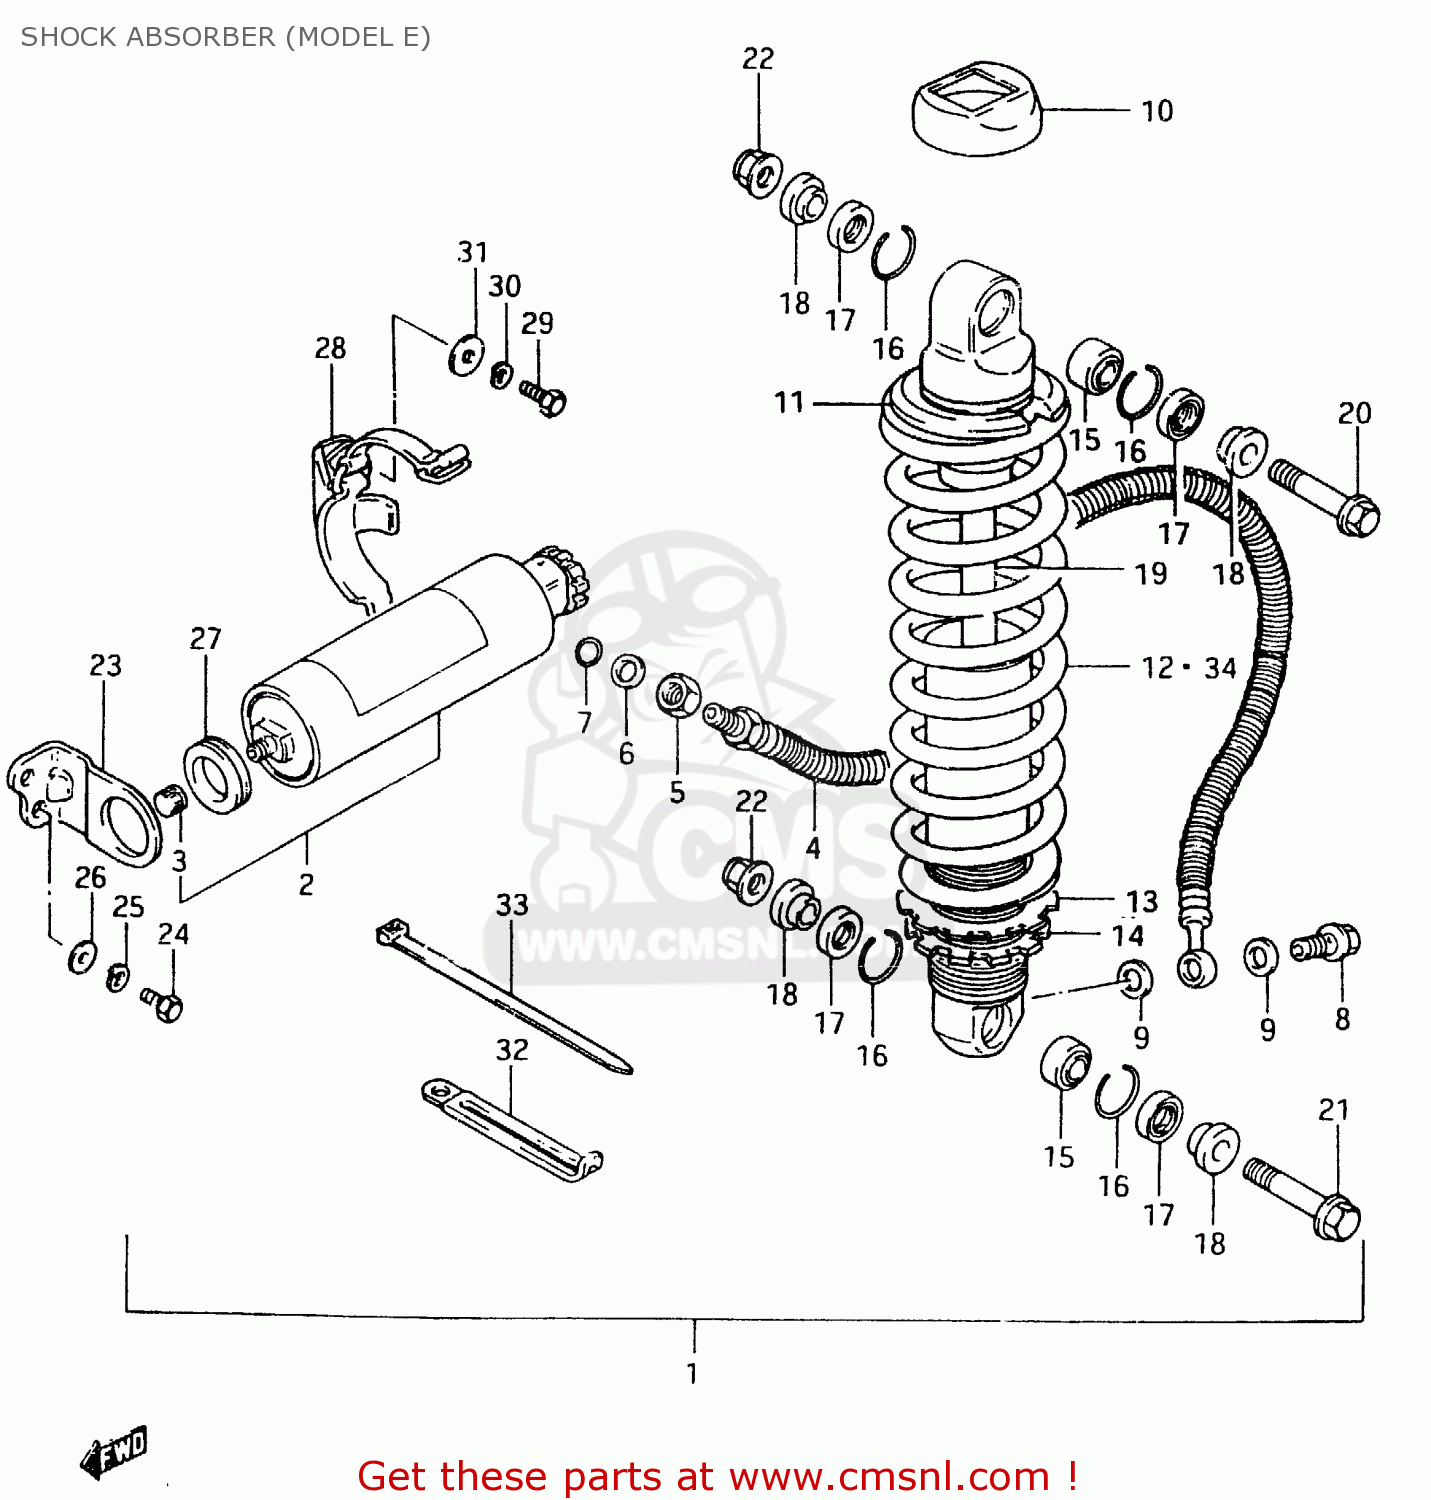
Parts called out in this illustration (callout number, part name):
1	ABSORBER ASSEMBLY,REAR SHOCK
2	RESERVE TANK,REAR SHOCK
3	CAP
4	HOSE,REAR SHOCK ABSORBER
5	NUT 12MM
6	WASHER,REAR SHOCK HOSE
7	O-RING,RESERVE TANK
8	BOLT,REAR SHOCK ABSORBER
9	GASKET (NAS)
10	CAP
11	GUIDE,REAR SHOCK ABSORBER SPRING
12	SPRING
13	GUIDE,SPRING
14	GUIDE,REAR SHOCK ABSORBER SPRING
15	BEARING,REAR SHOCK ABSORBER
16	RING
17	SEAL,DUST
18	SPACER
19	ROD,PISTON
20	BOLT,REAR SHOCK ABSORBER
21	BOLT(10X58)
22	NUT
23	BRACKET,RESERVOIR TANK
24	BOLT
25	LOCK WASHER
26	WASHER
27	CUSHION,RESERVOIR TANK
28	BRACKET,RESERVOIR TANK
29	BOLT, UPPER
30	LOCK WASHER
31	WASHER
32	CLAMP
33	CLAMP
34	SPRING
